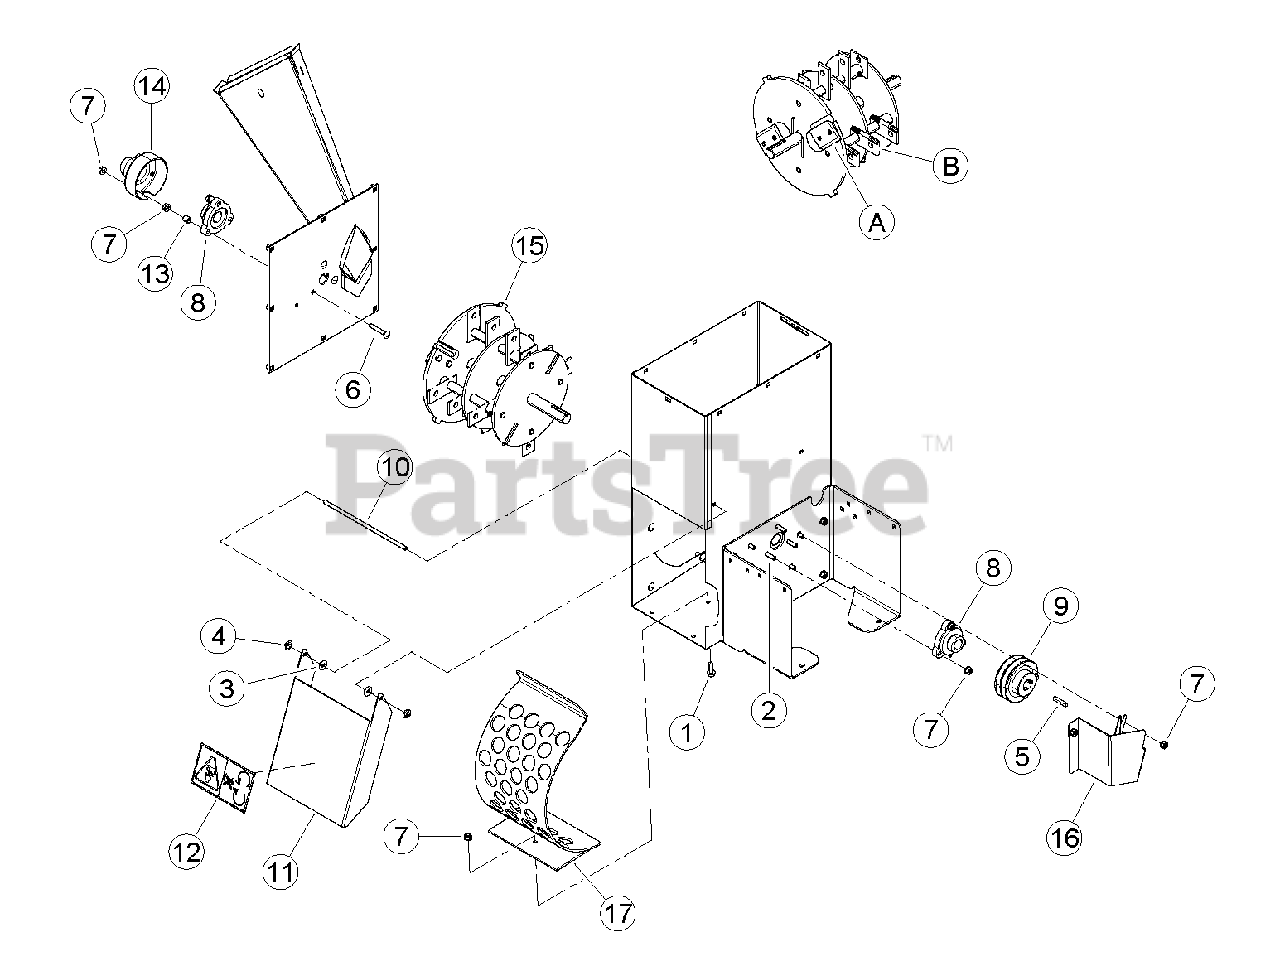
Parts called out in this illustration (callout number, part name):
1	BOLT, 5/16 X 1 FLANGE NC
2	BOLT, 5/16 X 1-1/4 CRG GR5 ZP
3	WASHER, 5/16 ID 7/8 OD NYLON FLAT
4	PUSHNUT, 5/16" ZP
5	KEY, 1/4 SQUARE X 1-1/2 LONG PLAIN
6	BOLT, 5/16 X 2CRG GR5 NC ZP
7	NUT, 5/16-18 NYLOCK-FLANGE
8	BEARING, 1" FLUSHMOUNT CAST W/COLLAR
9	PULLEY, 4 X 1 2A GROOVE
10	SHAFT, DOOR PIVOT
11	DOOR, 8 HP DISCHARGE W/ DECAL
12	DECAL, BLADE DANGER ISO
13	SPACER, .54 OD X .50" LG
14	CAP, ROTOR SHAFT END CAP
15	ASSEMBLY, BALANCED RENTAL ROTOR
16	SHIELD, LOWER
17	WELDMENT, WIDE COARSE TAPERED
A	KIT, TOOL STEEL BLADE
B	KIT, 3" WIDE SHREDDER KNIVES
